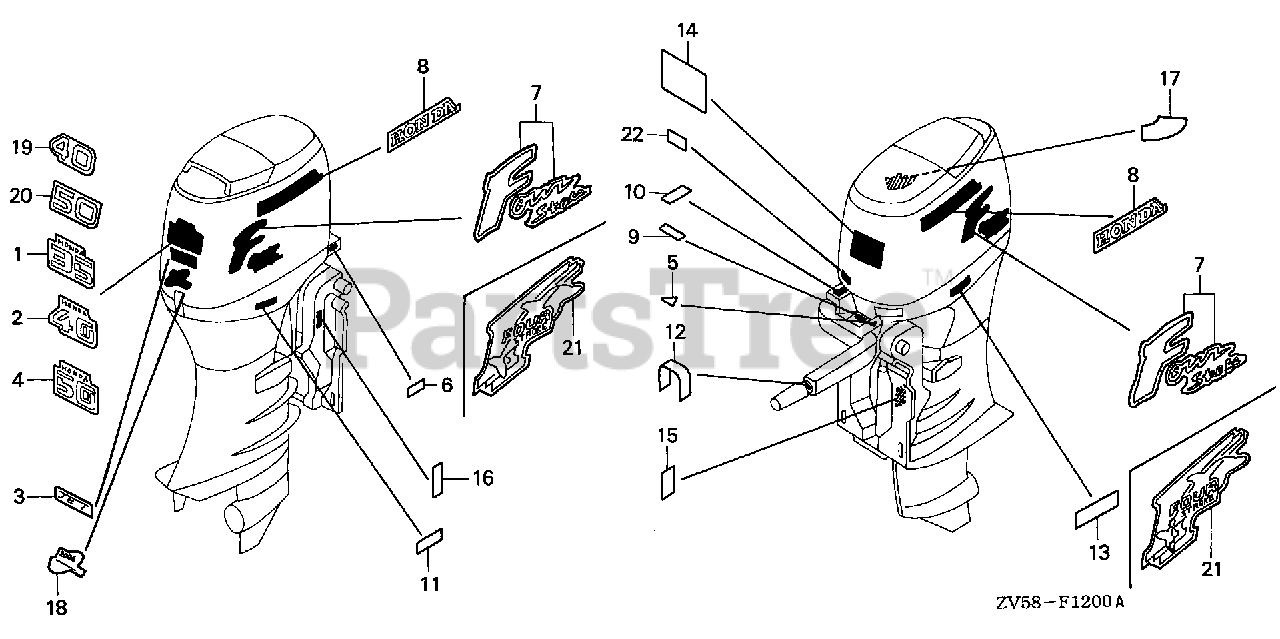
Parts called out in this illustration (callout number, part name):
8	MARK, SIDE STRIPE
9	LABEL, SPECIFICATION (NMMA)
11	LABEL, OIL CAUTION (ENGLISH)
13	LABEL, STORING CAUTION (ENGLISH)
14	LABEL, CAUTION OPERATOR (ENGLISH)
17	MARK, EMERGENCY START (ENGLISH)
19	MARK, RR. (40)
21	MARK, SIDE
22	MARK (E-SPEC)
